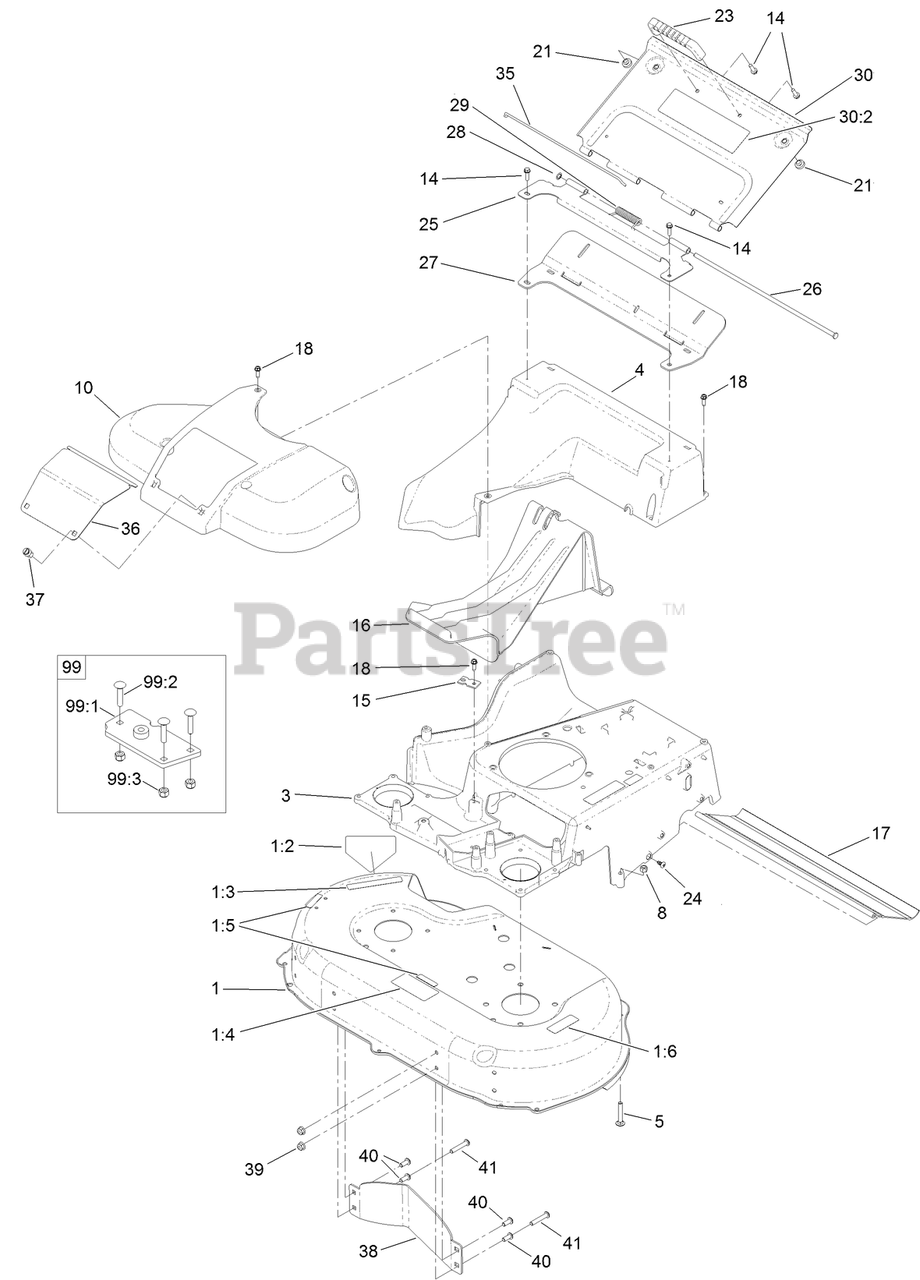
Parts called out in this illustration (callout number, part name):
1	DECK-30 INCH
1:2	DECAL-DANGER
1:3	DECAL-DANGER
1:5	DECAL-WARNING
1:6	DECAL-WARNING, BLOCK
3	FRAME
4	CHUTE
5	SCREW-CARR
8	NUT-LOCK, NI
10	COVER-BELT
14	SCREW-HWH
15	BRACKET-CABLE, TRACTION
16	PLUG-MULCH
17	SHIELD-TRAILING
18	SCREW-HWHTF
21	BUMPER
23	HANDLE-DOOR
24	SCREW-PTH
25	BRACKET-HINGE
26	PIN-HINGE
27	SEAL-DOOR
28	RING-RETAINING
29	SPRING-TORSION, COVER
30	REAR DOOR ASM
30:2	DECAL-WARNING
35	CLIP-SEAL
36	DOOR-ACCESS
37	FASTENER
38	BAFFLE-CONTROL
39	NUT-HF, NI
40	SCREW-HSBH
41	SCREW-HSBH
